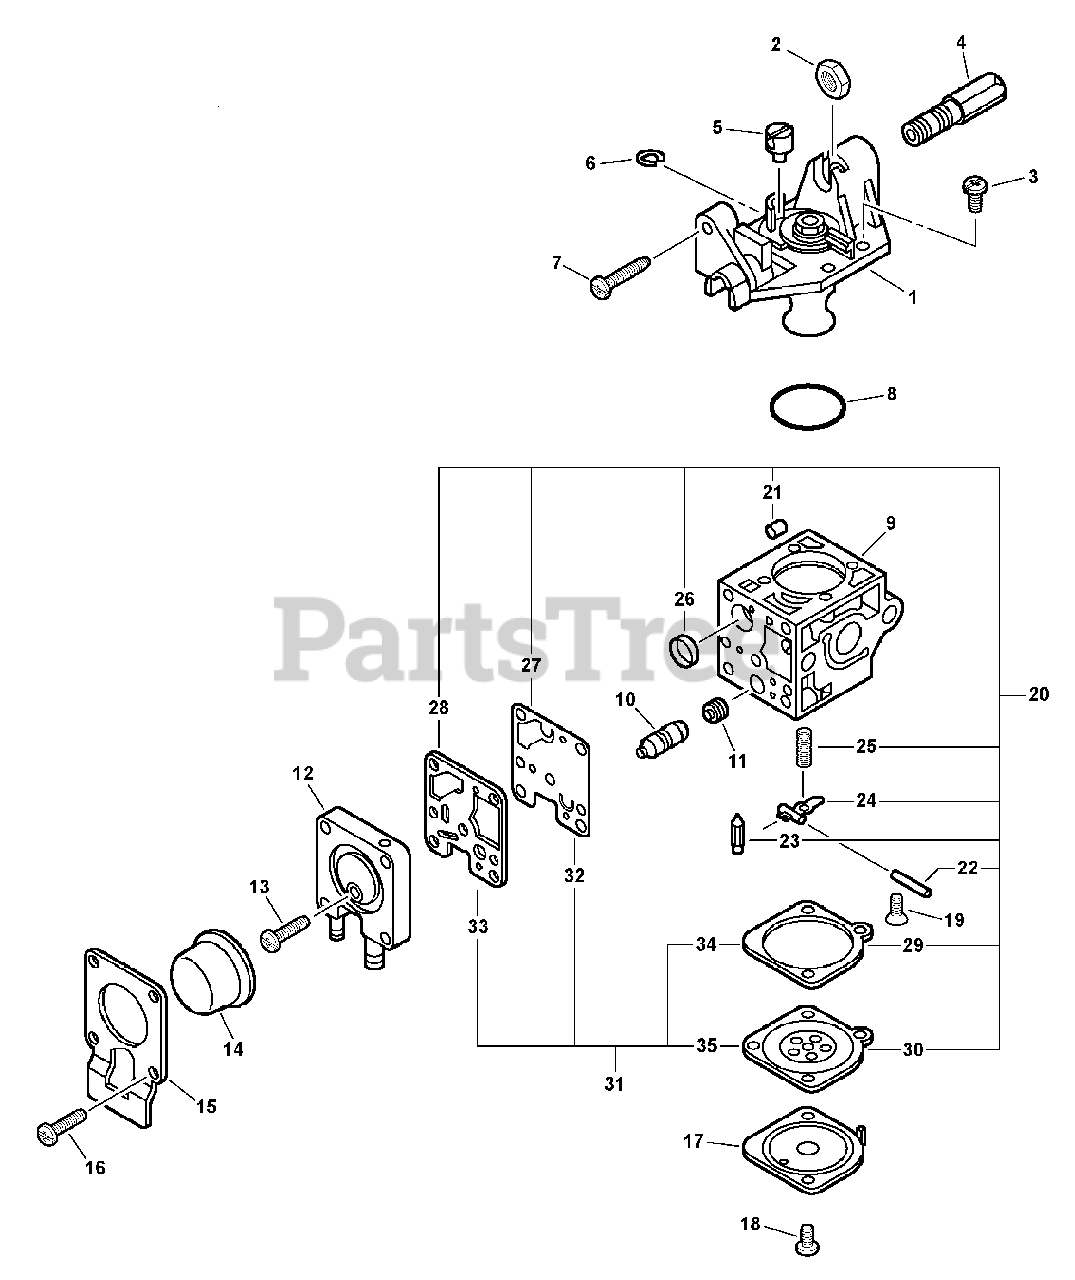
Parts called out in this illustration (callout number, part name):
1	Rotor Cover Asy
2	Nut, Cable
3	Screw, Rotor Cover Asy
4	Screw, Cable Adjust
7	Screw, Throttle Adjust
9	Body, Carburetor
10	Plug Kit
12	Purge Base Asy
13	Screw, Purge Base Asy
14	Bulb, Purge
15	Retainer, Purge Bulb
16	Screw, Purge Bulb Retainer
17	Cover, Diaphragm
18	Screw, Diaphragm Cover
19	Screw, Metering Lever Pin
20	Repair Kit
21	Roller, Guide
22	Pin, Metering Lever
23	Valve, Inlet Needle
24	Lever, Metering
25	Spring, Metering Lever
26	Strainer
27	Diaphragm, Pump
28	Gasket, Pump
29	Gasket, Metering
30	Diaphragm, Metering
31	Diaphragm/Gasket Kit
32	Diaphragm, Pump
33	Gasket, Pump
34	Gasket, Metering
35	Diaphragm, Metering
